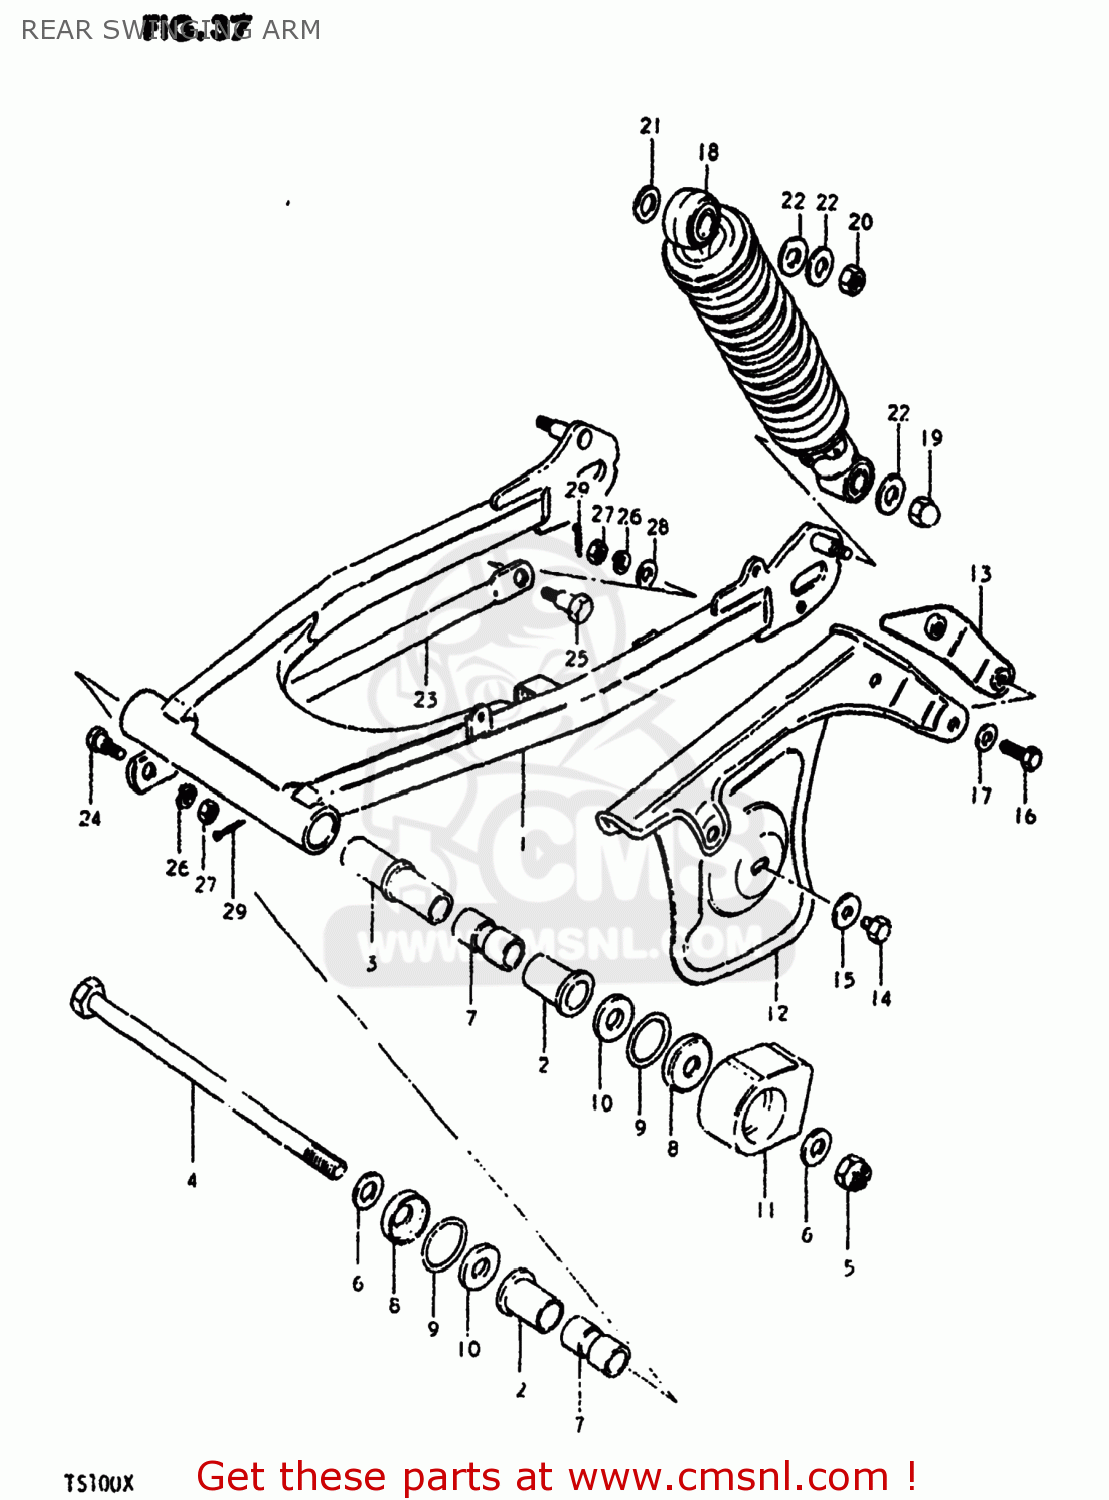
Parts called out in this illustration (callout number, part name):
1	SWING ARM ASSEMBLY,REAR
2	BUSH
3	SPACER,RR SWGARM PIVOT CTR
4	SHAFT,REAR SWING ARM
5	NUT 12MM
6	WASHER
7	SPACER,RR SWGARM PIVOT
8	COVER,SWGARM BUSH DUST SEAL
9	O RING(D:2,ID:24.5)
10	WASHER(12.5X24X2.3)
11	BUFFER,CHAIN TOUCH DEFENSE
12	CASE,CHAIN
13	REINFORCEMENT,CHAIN CASE
14	BOLT(6X8)
15	WASHER
16	BOLT, UPPER
17	WASHER
18	ABSORBER ASSEMBLY,REAR SHOCK
19	NUT, LOWER LH
20	NUT
21	WASHER
22	WASHER
23	TORQUE LINK,REAR
24	BOLT(8X22)
25	BOLT(8X26.5)
26	LOCK WASHER
27	NUT
28	WASHER
29	PIN
